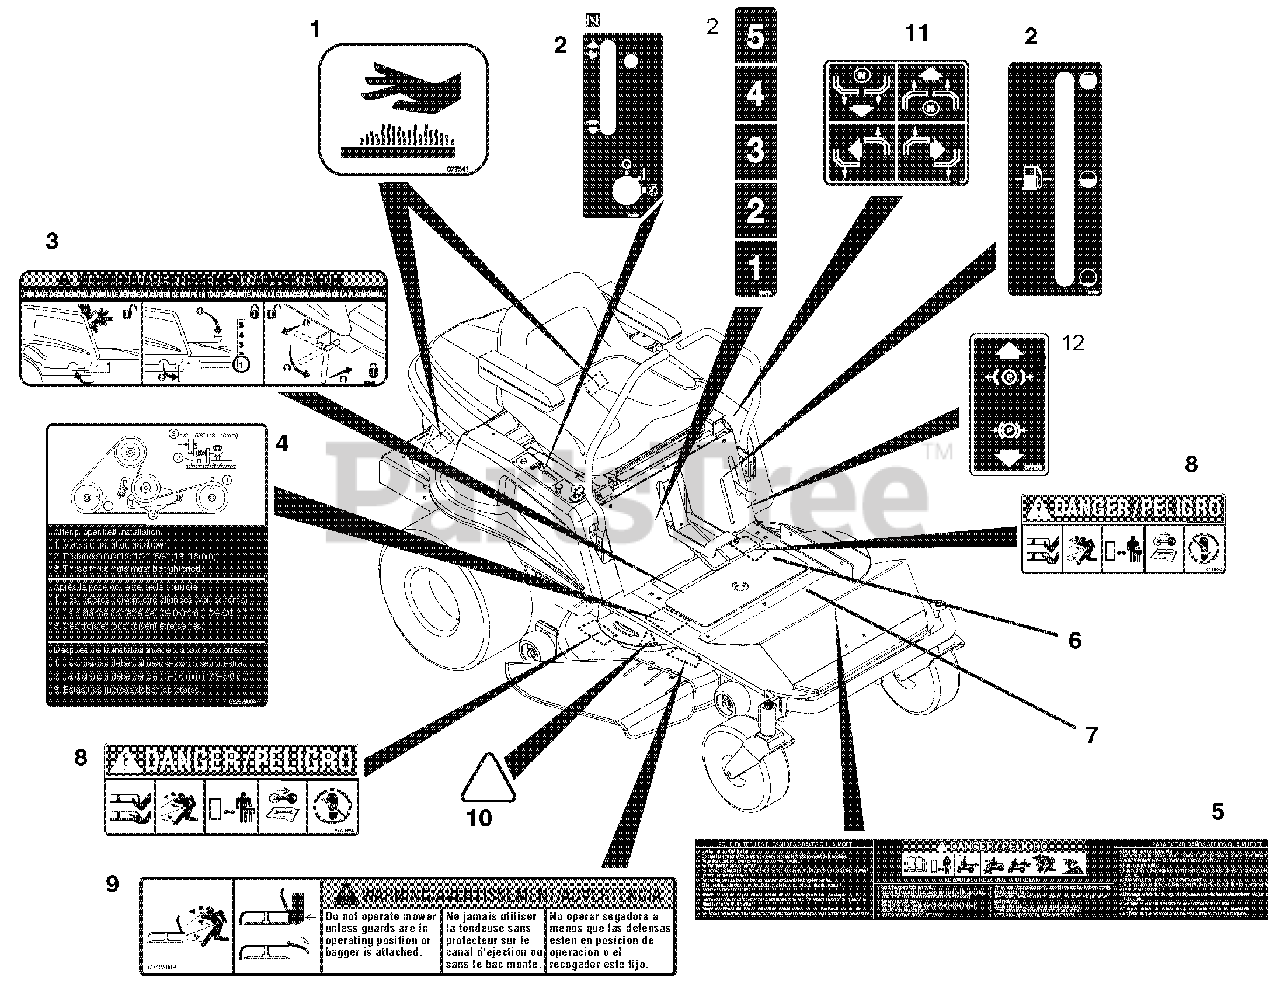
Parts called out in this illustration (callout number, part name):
1	Decal, Hot Surface
2	Decal-Instructional Set
3	Decal, Safe Deck Removal
4	Decal, Belt Diagram
5	Decal, Bilingual Danger
6	Non-Skid Cover
7	Non-Skid Cover
8	Decal, Mower Pan Head Danger
9	Decal, Warning
10	Decal, Blade Alignment
11	Decal, Instructional - Steering
12	Decal, Parking Brake Lever
